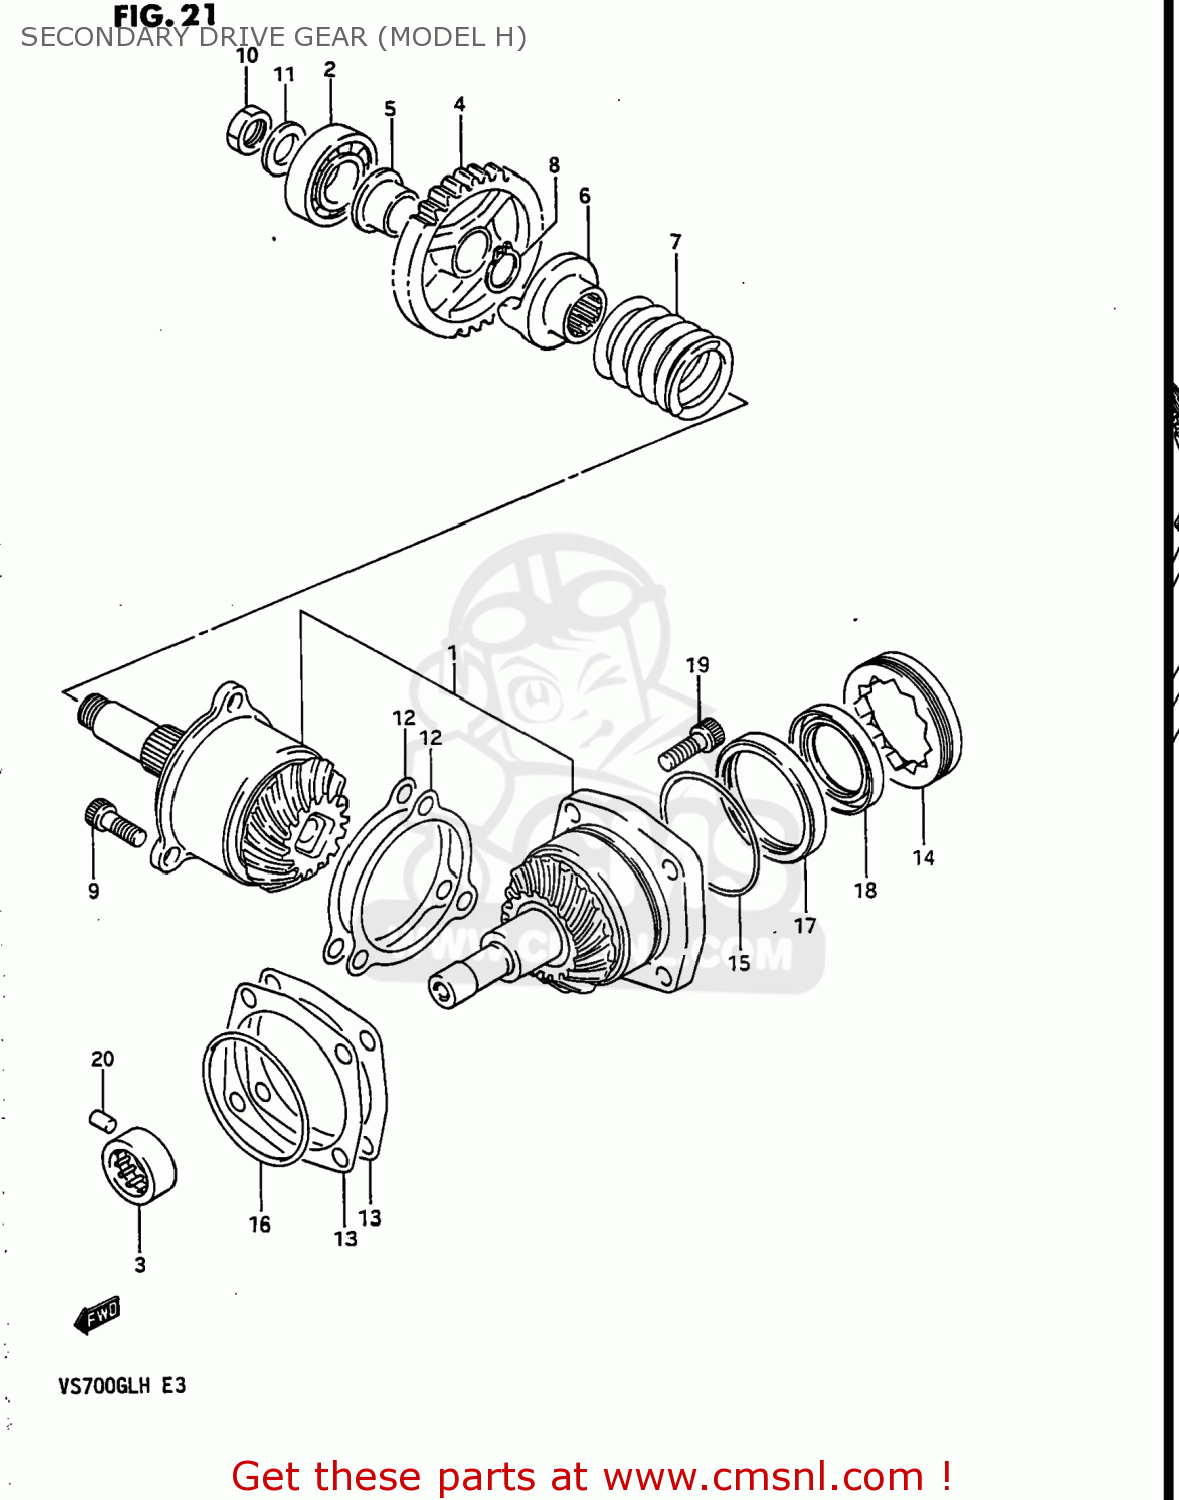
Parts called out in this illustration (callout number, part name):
1	GEAR & HOUSING SET,SECONDARY
2	BEARING(20X52X15)
3	BEARING(20X34X16)
4	GEAR,REDUCTION DRIVEN(NT:30)
5	BUSH,REDUCTION DRIVEN GEAR
6	DOG,OUTPUT CAM
7	SPRING
8	CIRCLIP,21MM
9	BOLT
10	NUT
11	WASHER(16X29X4)
12	SHIM,SECONDARY DRIVE
13	SHIM,SECONDARY DRIVEN HOUSING
14	STOPPER,SEC DRIVEN BEARING
15	O RING(D:1.2,ID:59.6)
16	O RING(D:2.1,ID:66.2)
17	HOUSING,OIL SEAL
18	SEAL,OIL(38X54X8.5)
19	BOLT
20	PIN
